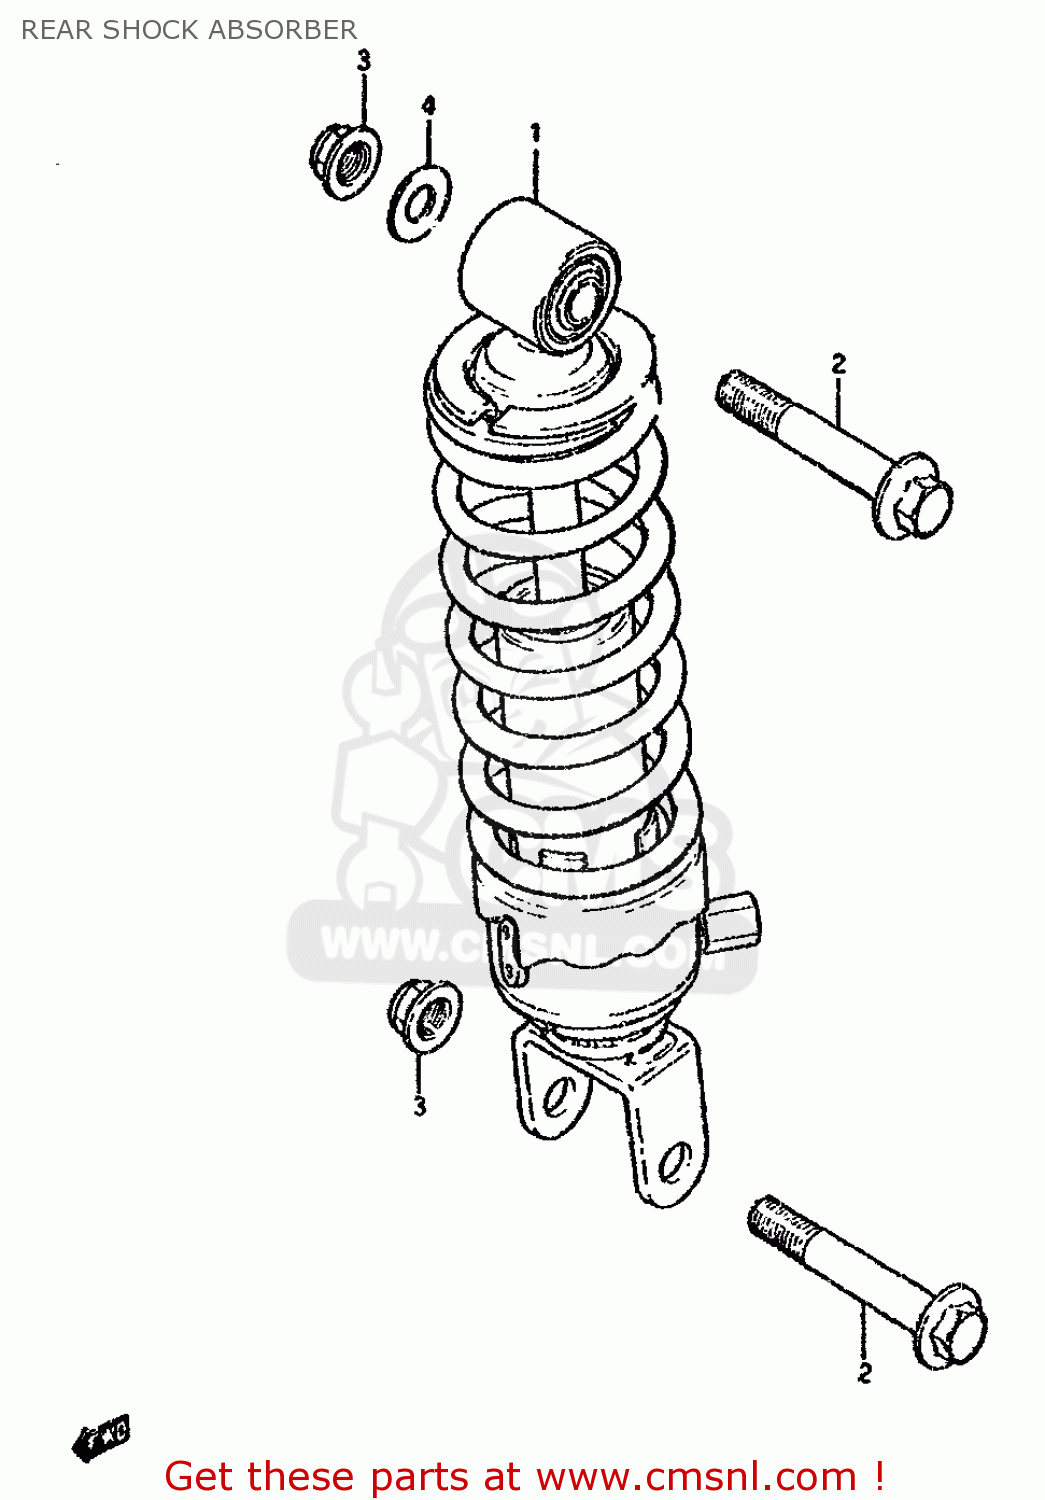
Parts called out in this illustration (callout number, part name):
1	ABSORBER ASSY,RR SHOCK
2	BOLT,RR SHOCK ABSORBER(10X51)
3	NUT
4	WASHER
